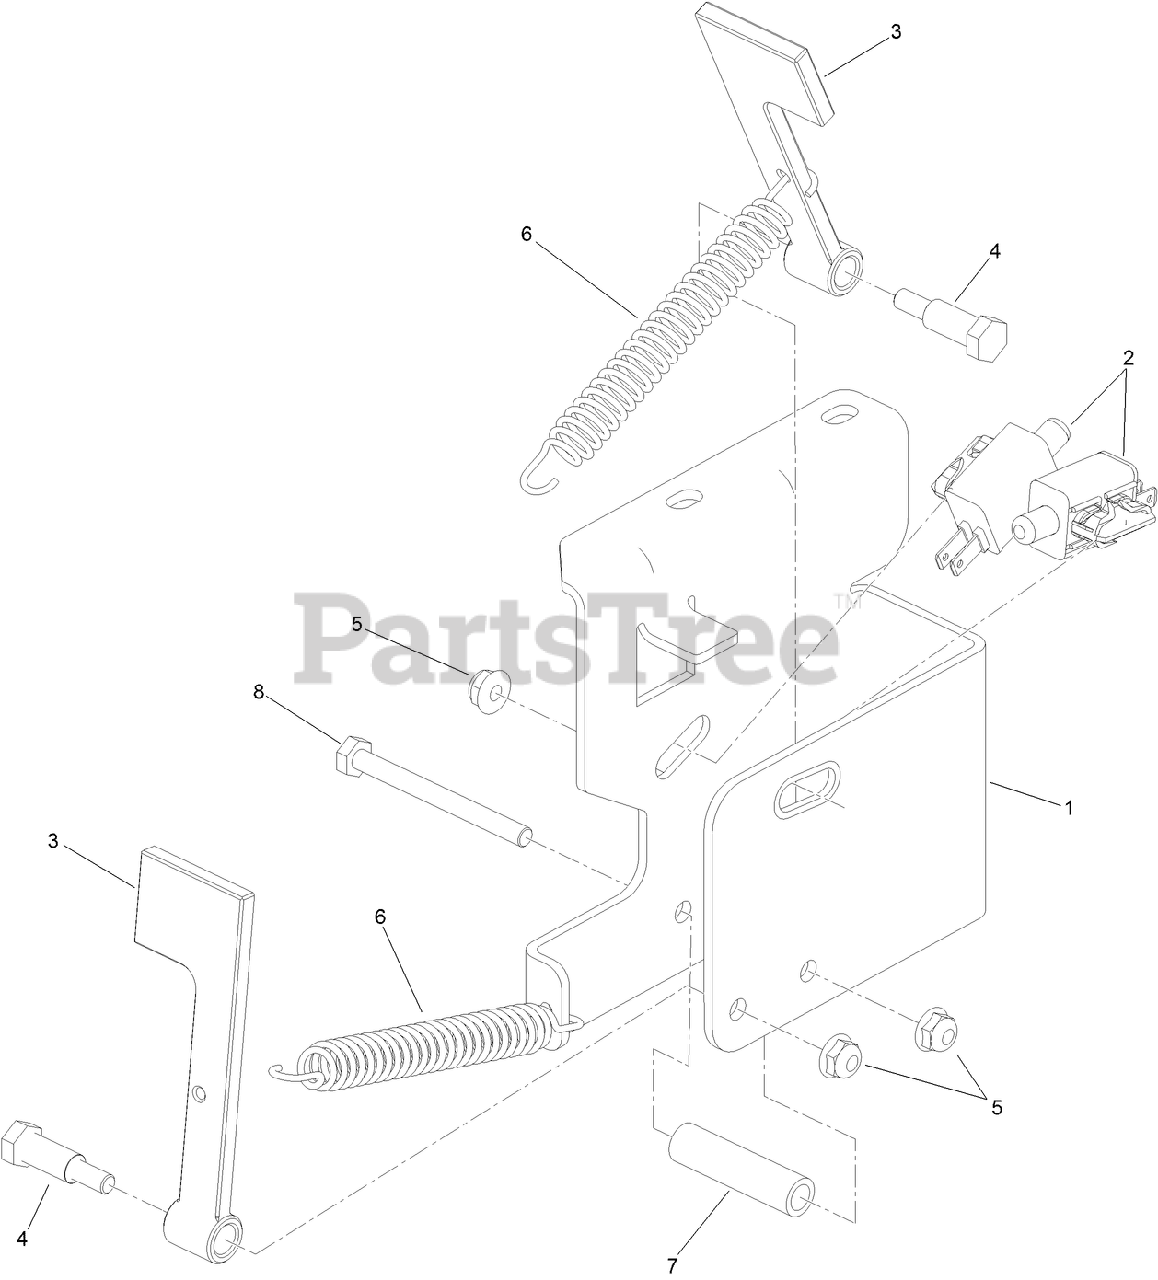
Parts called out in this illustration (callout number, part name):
1	BRACKET-SWITCH
2	SWITCH
3	ARM-SWITCH
4	BOLT-SHOULDER
5	NUT-HF
6	SPRING-EXTENSION
7	SPACER
8	SCREW-HH
